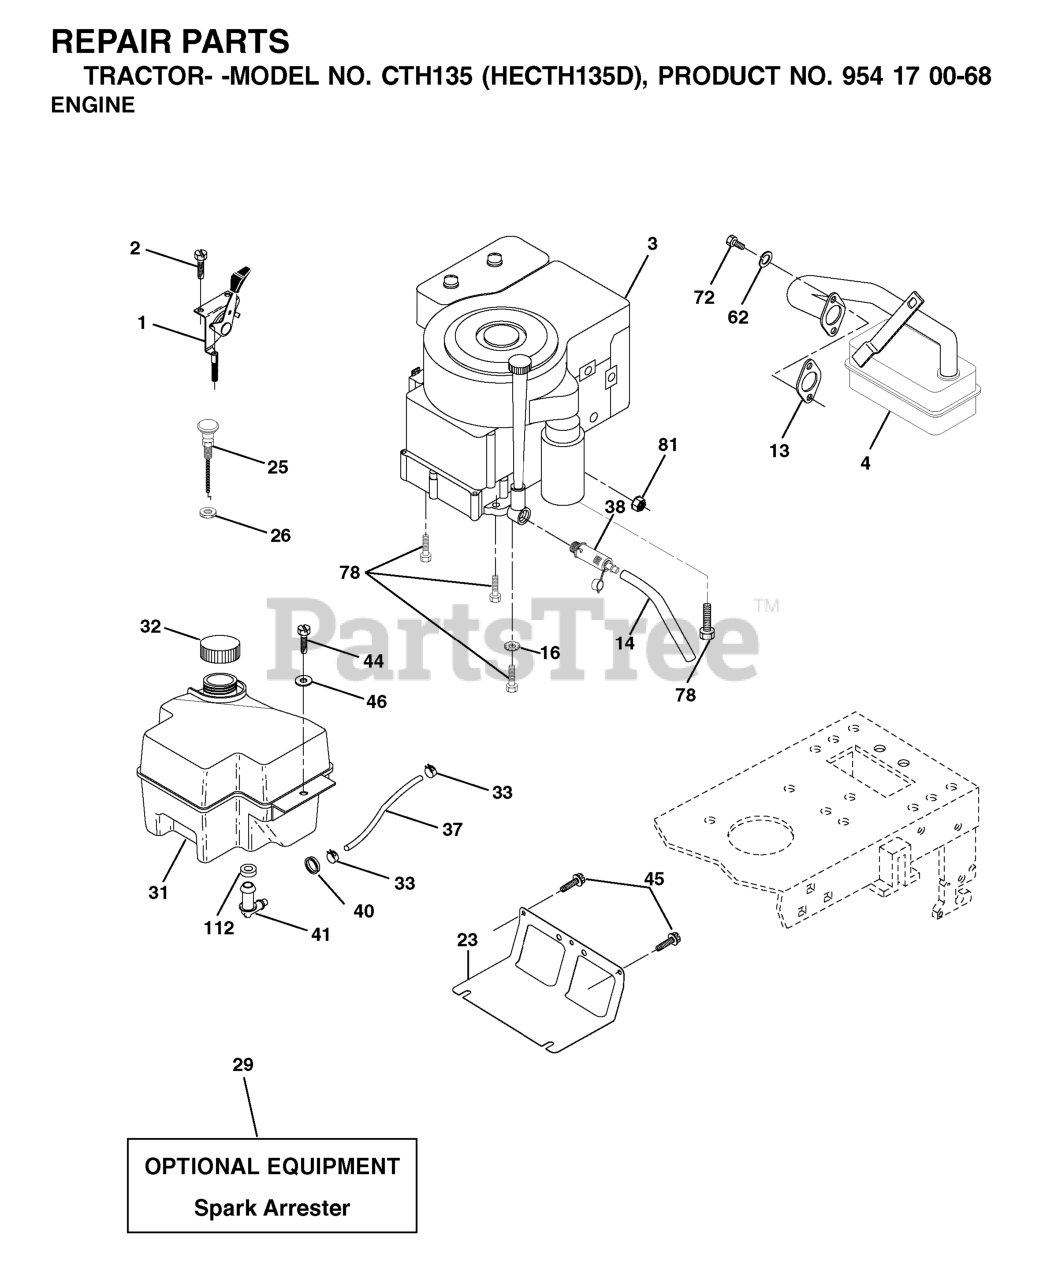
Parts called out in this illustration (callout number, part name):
1	CONTROL.THROTTLE/CHOKE.BLACK
2	SCREW
4	MUFFLER.LT.BRIGGS.14HP.IC/OHV
13	REPL BY 532 27 22-93
14	TUBE, DRAIN OIL ASM.
16	LOCKWASHER
23	SHIELD.BROWNING.DBR.GUARD
26	Nut Keps 3/8 - 24 UNF
29	KIT.SPARK ARRESTOR 794945 B&S
31	GAS TANK 2GAL
32	FUEL CAP
33	HOSE CLAMP
37	LINE.FUEL.20
38	PLUG, OIL DRAIN EASY
40	BUSHING.SNAP.NYL.BLK.
41	STEM FUEL TANK
44	SCREW HEXWSHR 1/4-20X3/4
45	SCREW, 3/8-16X3/4
62	WASHER.LOCK.HVY.HLCL.SPR.5/16
72	SCREW
78	SCREW.3/8-16
81	NUT
112	BUSHING OUTLET T
